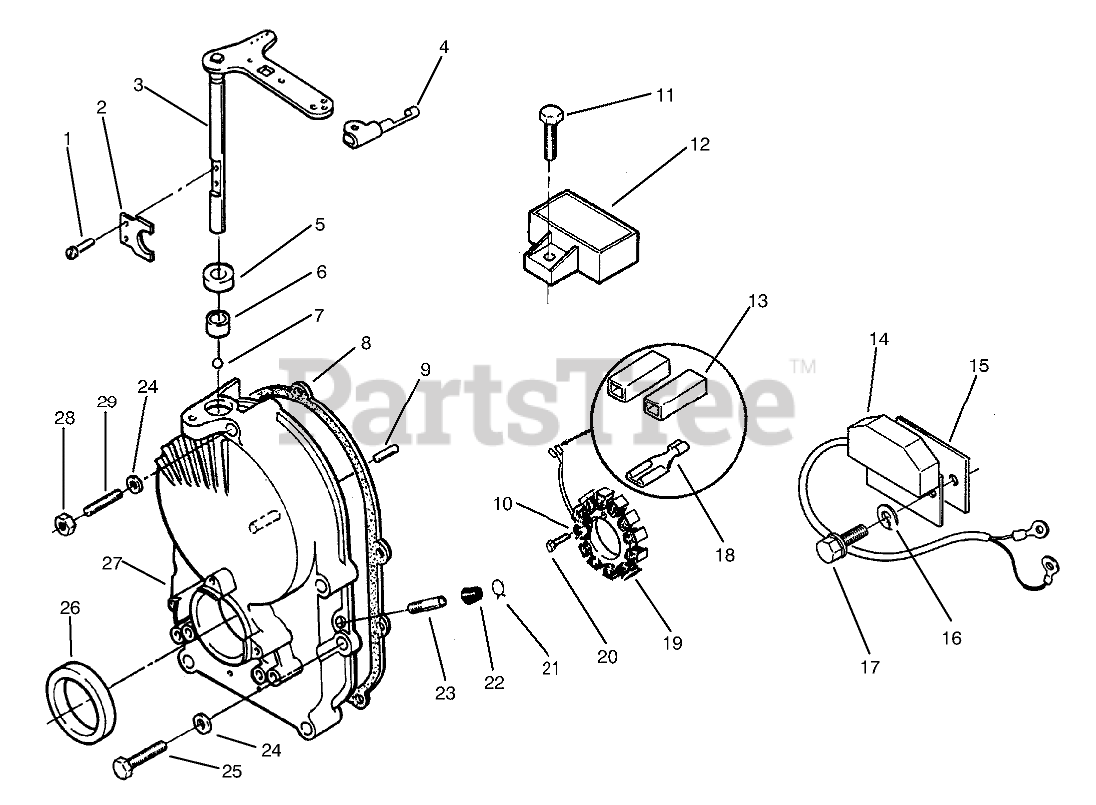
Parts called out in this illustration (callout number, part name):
1	SCREW-PAN HD
3	SHAFT AND ARM
4	RETAINING CLIP
6	BEARING
8	GEAR CASE MTG GASKET
9	PIN-DOWEL
10	WASHER-LOCK
11	SCREW-HWH
12	REGULATOR
13	BODY-TERM. CONNECTOR KIT
14	CONTROL-IGNITION
15	INSULATOR-IGN MODULE
16	WASHER-LOCK
17	Bolt
18	TERMINAL
19	KIT - STATOR
20	Screw-HH
21	CLAMP
22	CAP-FUEL OUTLET
23	TUBE-PORT, VACUUM
24	WASHER
25	HEX-HEAD CAP SCREW
27	GEAR-CASE KIT
28	NUT-GEAR COVER
29	STUD-GEAR COVER
